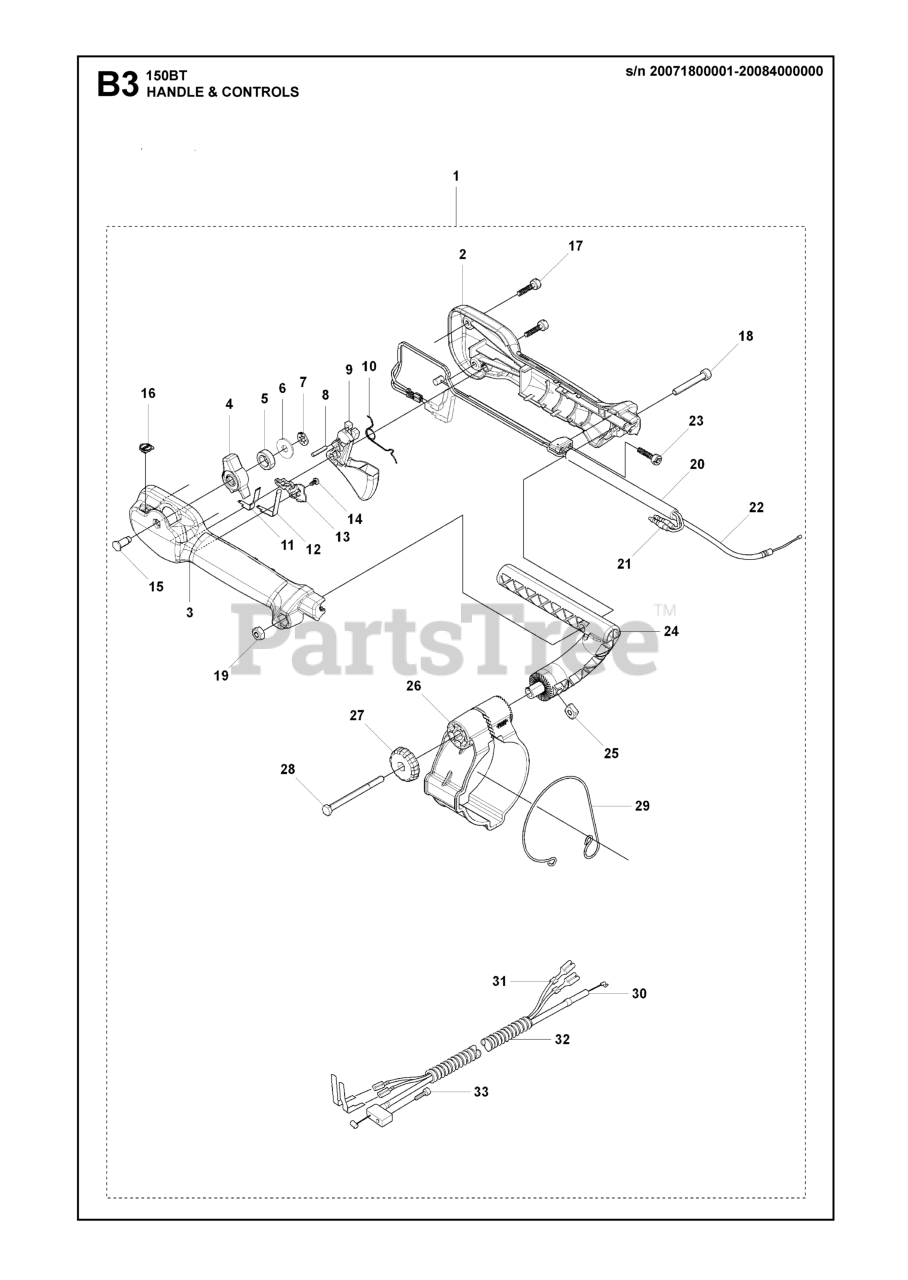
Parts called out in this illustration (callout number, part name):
1	HANDLE ASSY.
5	SPRING RUBBER
9	THROTTLE TRIGGER
11	CONTACT SPRING
12	CONTACT SPRING
18	SCREW
24	BRACKET
26	HOLDER TH
